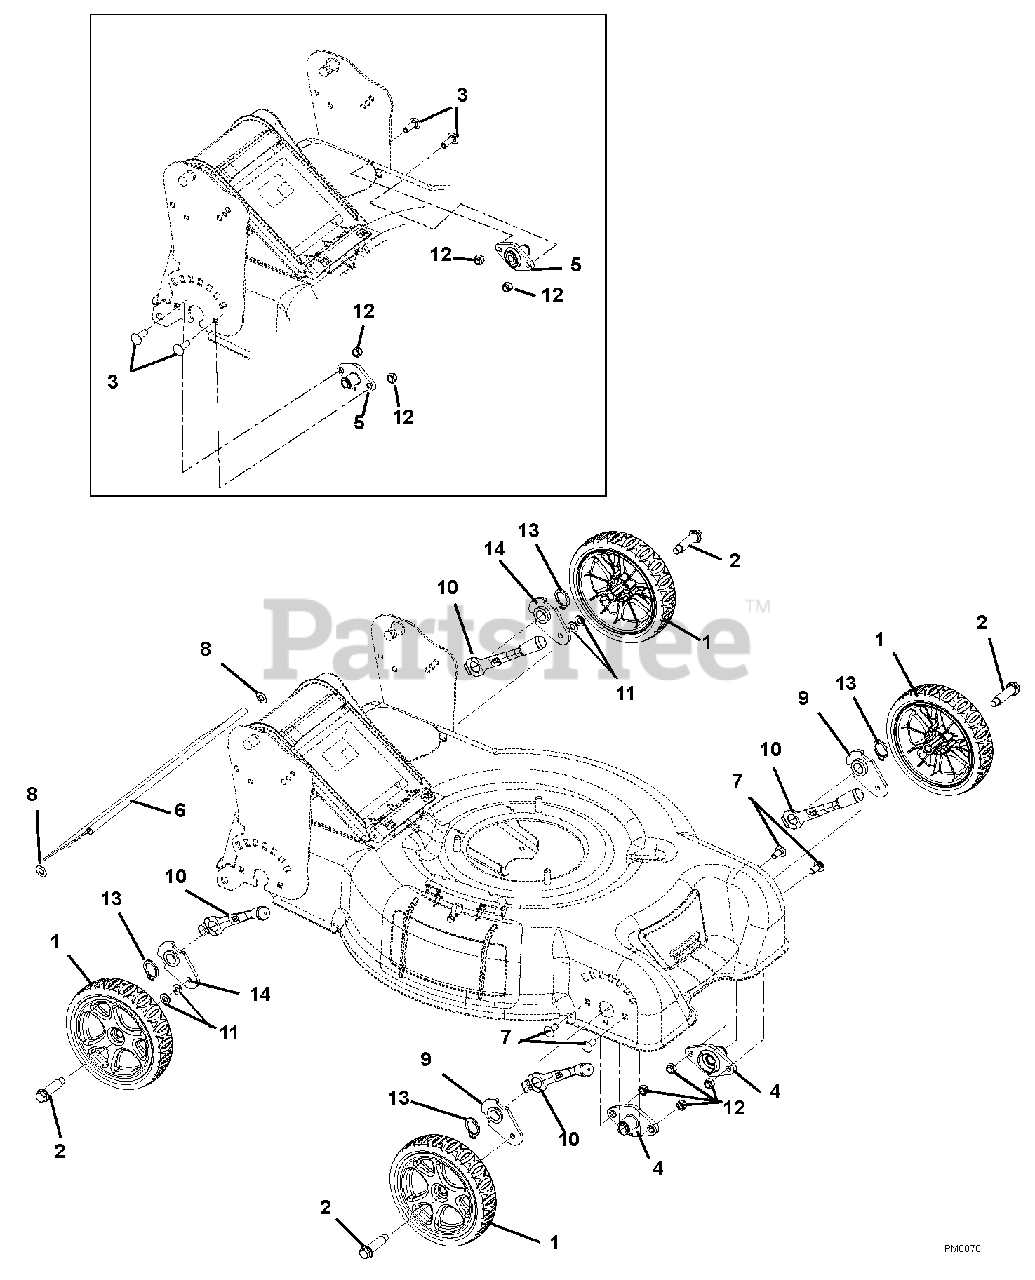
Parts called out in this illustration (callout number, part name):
1	WHEEL-8.5" WBLM ASSY
2	BOLT, WHEEL SHOULDER
3	@BLT-RDHDSQNK .31-18X1.00 G5YZ
4	WHEEL MOUNT HUB
5	KIT, WHEEL MOUNT HUB SERVICE
6	GUARD, WBLM
7	@BLT-RHDSSQNK .31-18X.75 G5YZ
8	RETAINER, .38 PUSH-ON
9	PLATE, FRONT WHEEL MOUNT
10	HANDLE, HOC
11	@WSHR-FL-STL.406X.812X.065 YWZ
12	@NUT-LK-TOP-FLG .31-18 YWZC
13	RG-RTNG-EXT .689X.078
14	PLATE, REAR WHEEL MOUNT
